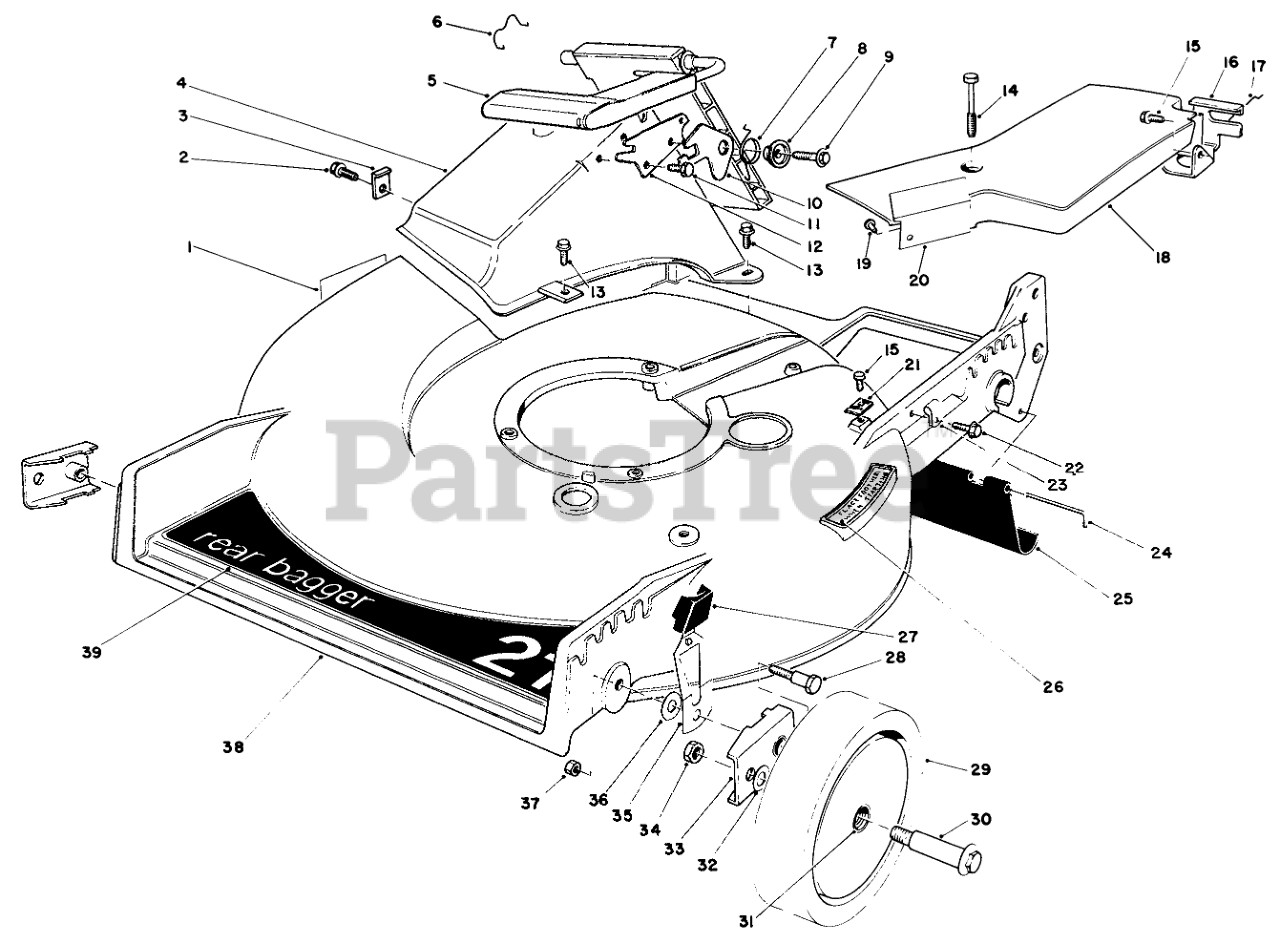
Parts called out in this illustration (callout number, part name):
1	DECAL-DANGER
2	SCREW
3	TUNNEL CLIP
4	Tunnel Discharge
5	Discharge Door Assembly
6	DOOR RET SPRING
7	TORSION SPRING
8	DOOR SPACER
9	SCREW-HWH
10	SAFETY LATCH
11	SCREW-PLASTITE
12	DOOR LATCH PLATE
13	Screw-Self Tapping Hex Washer Hd.
14	SCREW-HHFTF
15	SCREW-HWHTF
16	Bracket-Traction Adj.
17	RETAINER-CABLE
18	Belt Cover Assembly (Incl. Ref. #19 & 20)
19	RIVET-HEAD, FLAT
20	HEAT SHIELD
21	Cable Clamp
22	SCREW
23	CLAMP-CABLE
24	ROD-SHIELD
25	SHIELD-TRAILING
26	STEP PAD DECAL
27	KNOB-ARM
28	PIVOT SCREW
29	Wheel & Tire Assembly (Incl. Ref. #31)
30	WHEEL BOLT
31	BUSHING
32	WASHER
33	HP PIVOT ARM ASM
34	NUT-LOCK
35	Spring Arm
36	WASHER-PIVOT
37	NUT-LOCK, NI
38	Housing
39	DECK DECAL
